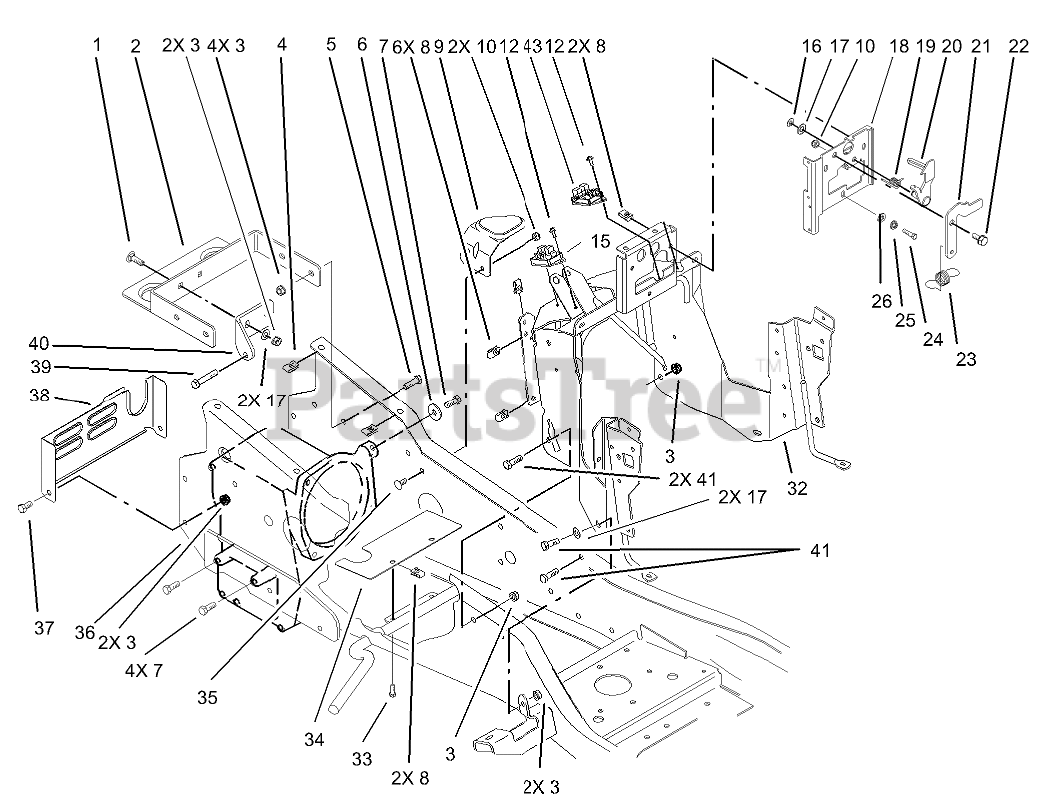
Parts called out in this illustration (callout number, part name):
1	BOLT-CARR
2	Support-Gas Tank
3	NUT-LOCK, NI
4	NUT-U
5	SCREW-HH
6	WASHER
7	SCREW-HH, LOCK
9	SUPPORT-TANK, FUEL
10	NUT-LOCK, NI
12	SCREW-HWH
15	MODULE-CRUISE
16	RING-RETAINING
17	WASHER-FLAT
18	BRACKET-LATCH
19	SPRING-LEVER, LATCH
20	LEVER-LATCH
21	LATCH-LEVER, TENSION
22	BOLT-SHOULDER
23	SPRING-LEVER, LATCH
24	SCREW-HH
25	WASHER-LOCK
26	WASHER-FLAT
32	TOWER ASM
33	SCREW-HH
34	BAFFLE-FAN
35	SCREW-CARR
37	SCREW-HH
38	COVER-REAR
39	SCREW-HH W/LOCTITE
40	Strap-Torque
41	SCREW-HH
43	MODULE-CLUTCH
